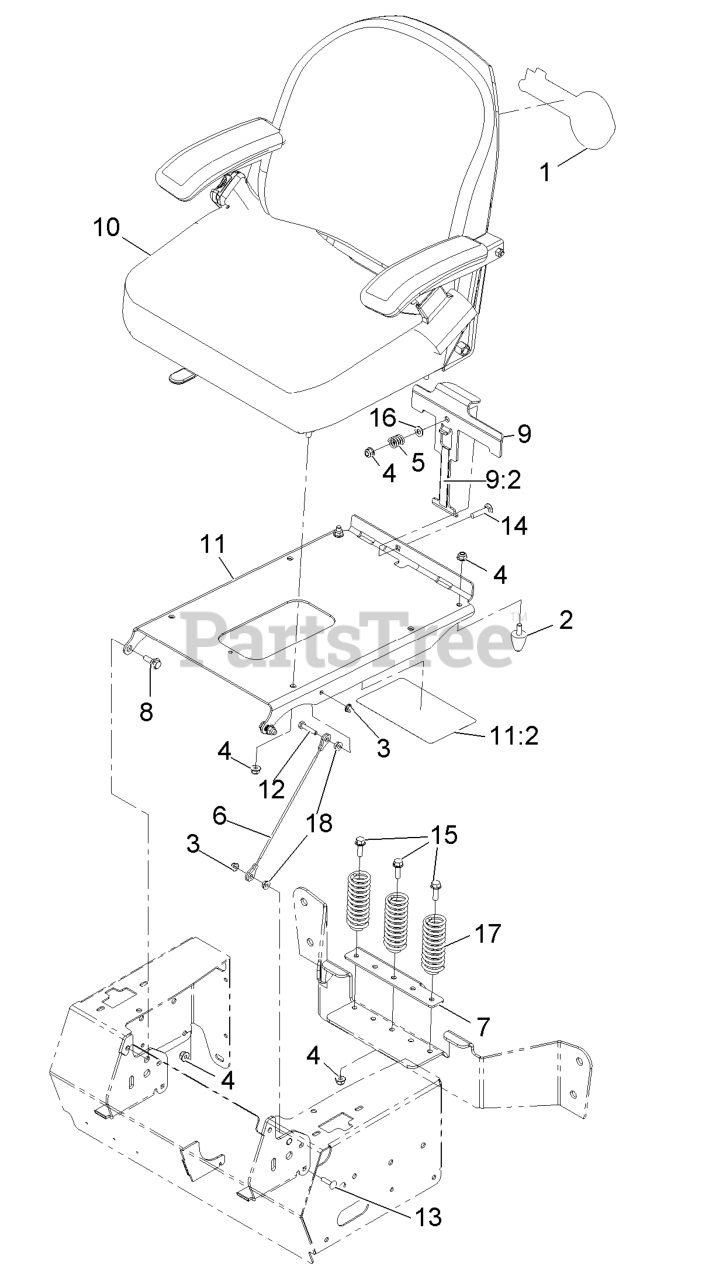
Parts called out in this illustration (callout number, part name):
1	DECAL,EXMARK LOGO
2	BUMPER-SEAT
4	NUT-HF, NI
5	SPRING-COMPRESSION
6	CABLE-STOP, SEAT
7	CATCH,SEAT LATCH
8	SCREW-SHOULDER
9	ASM-SEAT LATCH
9:2	STRIP-POLY WEAR
11	PLATE, SEAT W/DECALS
11:2	DECAL-SERVICE AID
12	SCREW-HH
13	SCREW-CARR
14	BOLT-CARR
15	SCREW-HHF
16	WASHER-PLAIN
17	SPRING-COMPRESSION
